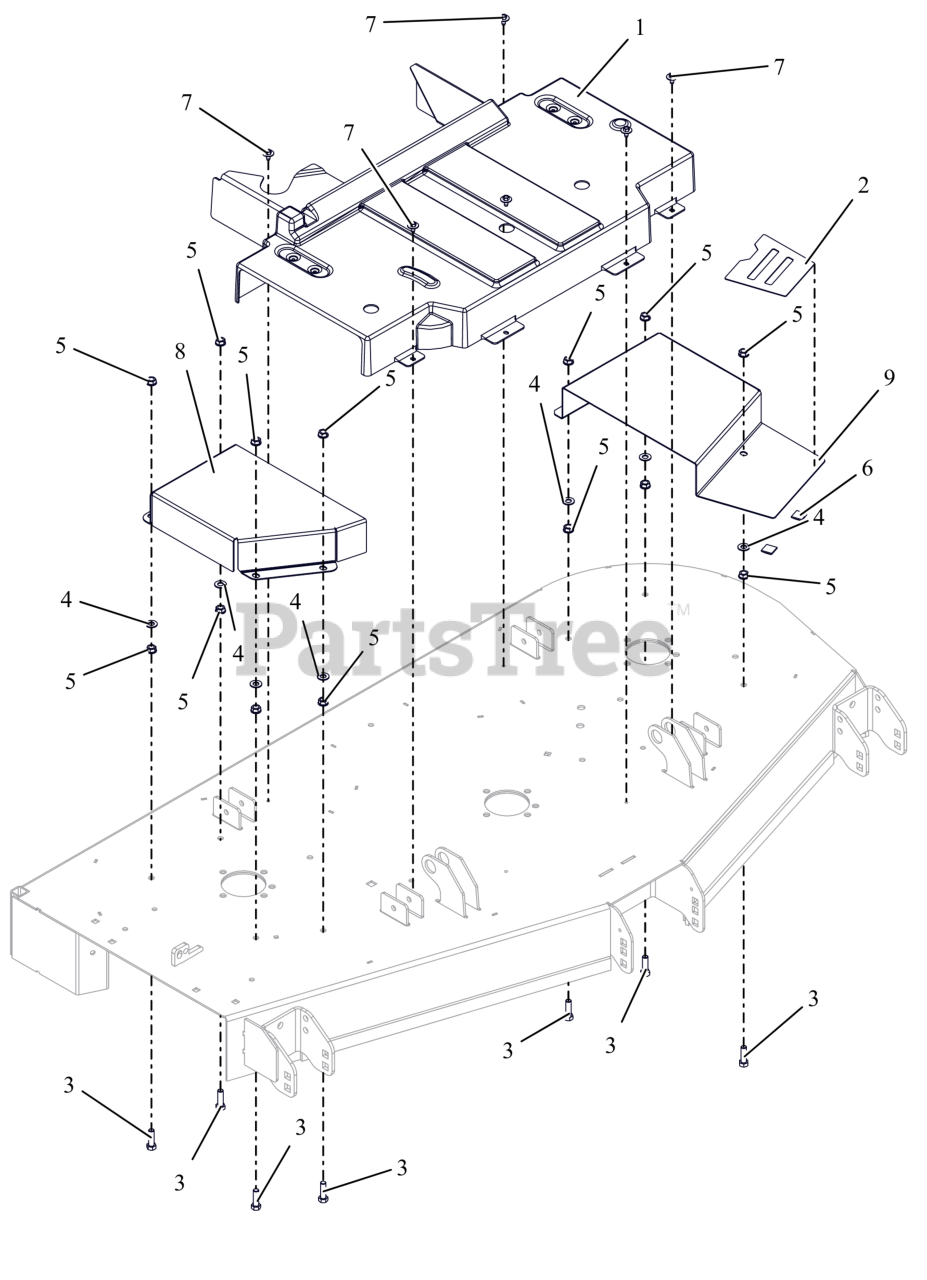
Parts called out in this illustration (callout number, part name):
1	GUARD, CENTER DECK SPINDLE CE
2	GRIP TAPE 52-60 BELT COVER
3	BLT, HEX .38-16X1.25 G5 ZCC
4	WSHR,FLT .406X.812X.065 ZCC
5	NUT, SPNLK-FLG .38-16 G5 ZCC
7	SCR, TAP .25-20X.50 LG HWH ZCC
8	GUARD,BELT 52" RIGHT CE
9	GUARD, BELT 60" LEFT CE (ORANGE)
